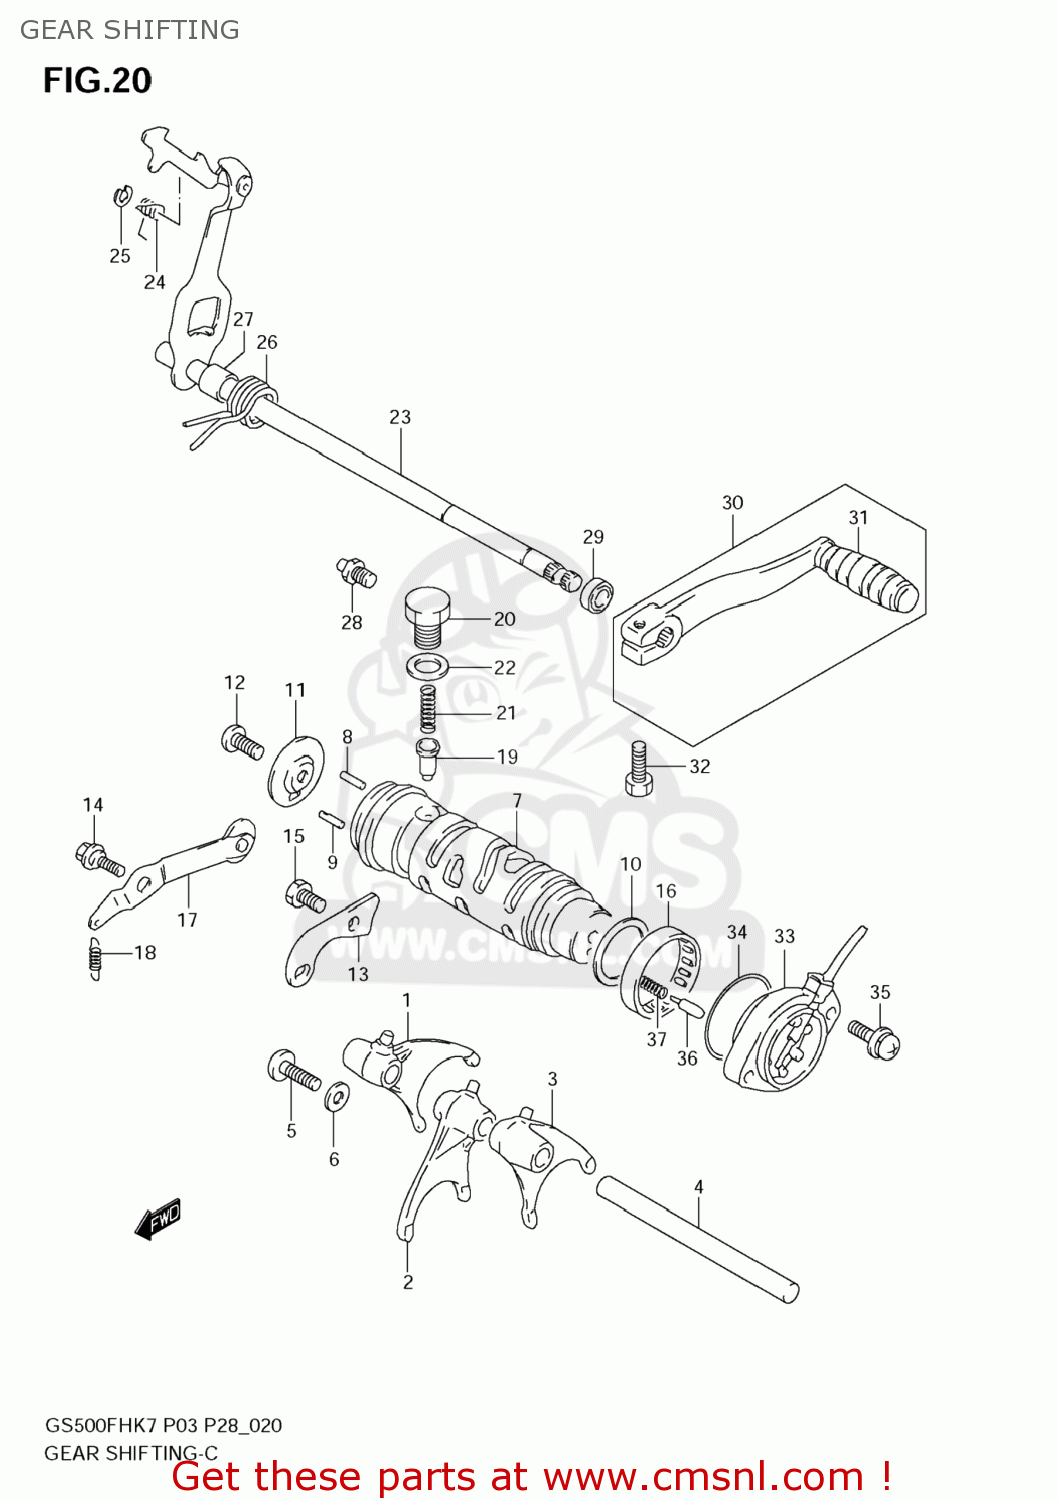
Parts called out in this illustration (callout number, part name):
1	FORK,GEAR SHIFT NO.1
2	FORK,GEAR SHIFT NO.2
3	FORK,GEAR SHIFT NO.2
4	SHAFT,GEAR SHIFT FORK
5	SCREW(6X8)
6	WASHER
7	CAM,GEAR SHIFT
8	PIN(4X18.5)
9	PIN
10	SHIM(26X32.5X0.3)
11	RETAINER,GEAR SHIFT CAM DR PIN
12	SCREW
13	GUIDE,GEAR SHIFT CAM
14	BOLT(6X14.6)
15	BOLT(6X16)
16	BEARING(40X47X12)
17	STOPPER,GEAR SHIFT CAM NO.1
18	SPRING
19	STOPPER,GEAR SHIFT CAM NO.2
20	HOLDER,GEAR SHIFT CAM STOP SPR
21	SPRING
22	GASKET(13.8X18.8X4.8) (NAS)
23	SHAFT,GEAR SHIFT
24	SPRING
25	E RING
26	SPRING
27	SPACER(12X20X15.3)
28	STOPPER,GEAR SHIFT ARM
29	OIL SEAL
30	LEVER ASSY,GEAR SHIFT
31	RUBBER,GEAR SHIFT PEDAL
32	BOLT
33	BASE ASSY,GEAR SHIFT TERMINAL
34	O RING(D:2.4,ID:26.2)
35	SCREW
36	PIN(5X15.5)
37	SPRING
